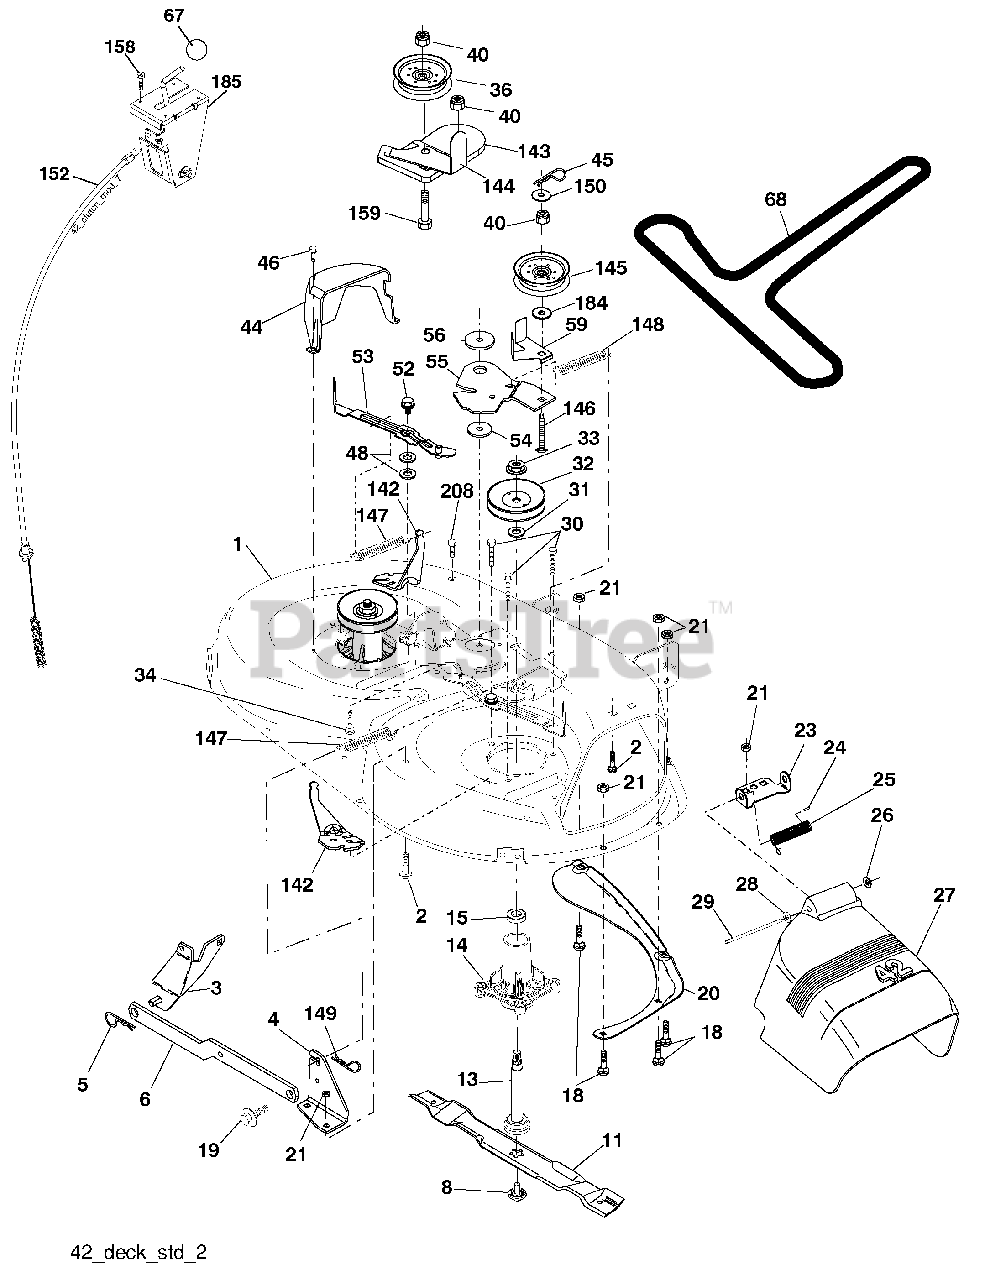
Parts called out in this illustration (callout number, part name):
1	Mower Deck Assembly, 42"
2	Bolt
3	Bracket Asm Fr. Sway Bar 3/42
4	Bracket Asm Deck 42" Sway Bar
5	Retainer Spring
6	Bar Sway Deck
8	Bolt/Washer Asm. 7/16-20 unf
11	Blade Mower 42” Hi-Lift (for bagging and discharging)
13	Shaft As m. Mandrel
14	Housing Mandrel
15	Bearing, Ball, Mandrel
18	Bolt, Carriage 5/16-18 x 5/8
19	Bolt, Shoulder
20	Baffle, Vortex
21	Nut
23	Bracket, Deflector Mower 42"
24	Cap, Sleeve 80 x 112 Blk Mower
25	Spring, Torsion, Deflector 2 52
26	Nut, Push Phos & Oil
27	Shield, Deflector 42" Blk
28	Washer 11/32 x 5/8 x 16 Ga.
29	Rod, Hinge 42" 6 75 w/G
30	Screw Thdrol
31	Washer, Spacer Mower Vented
32	Pulley, Mandrel
33	Nut, Toplock
34	Bolt Carr SH 3/8-16 x 1-1/2 Gr.5
36	Pulley, Idler, Flat
40	Nut Lock 3/8-16
44	Guard, Mandrel, LH
45	Retainer
46	Screw, Thdrol 1/4-20 x 5/8 T
48	Washer, Hardened
52	Bolt, Shoulder 5/16-18 unc
53	Arm Assembly, Pad, Brake
54	Washer, Hardened
55	Arm, Idler
56	Spacer, Retainer
59	Guard TUV Idler
67	Knob Round
68	V-Belt, 42" Mower
142	Anchor Spring Brake Mower
143	Bracket Arm Idler 42"
144	Keeper Belt 42" Clutch Cable
145	Pulley Idler Flat
146	Bolt Carriage Idler
147	Spring Extension
148	Spring Return Idler
149	Retainer Spring Yellow
150	Washer 9/32 x 3/4 x 10 Ga.
152	Clutch Cable 42"
158	Screw Hex Thd Cut 1/4-20 x 1/2
159	Bolt Rdhd Sqn 3/8-16 unc x 1-3/4
184	Washer 13/32 x 7/8 x 10 Ga.
185	Head Asm Cable Clutch\
208	Screw Thdrol 3/8 x 16 x 1/2
208	Mandrel Assembly
208	Replacement Mower, Complete
